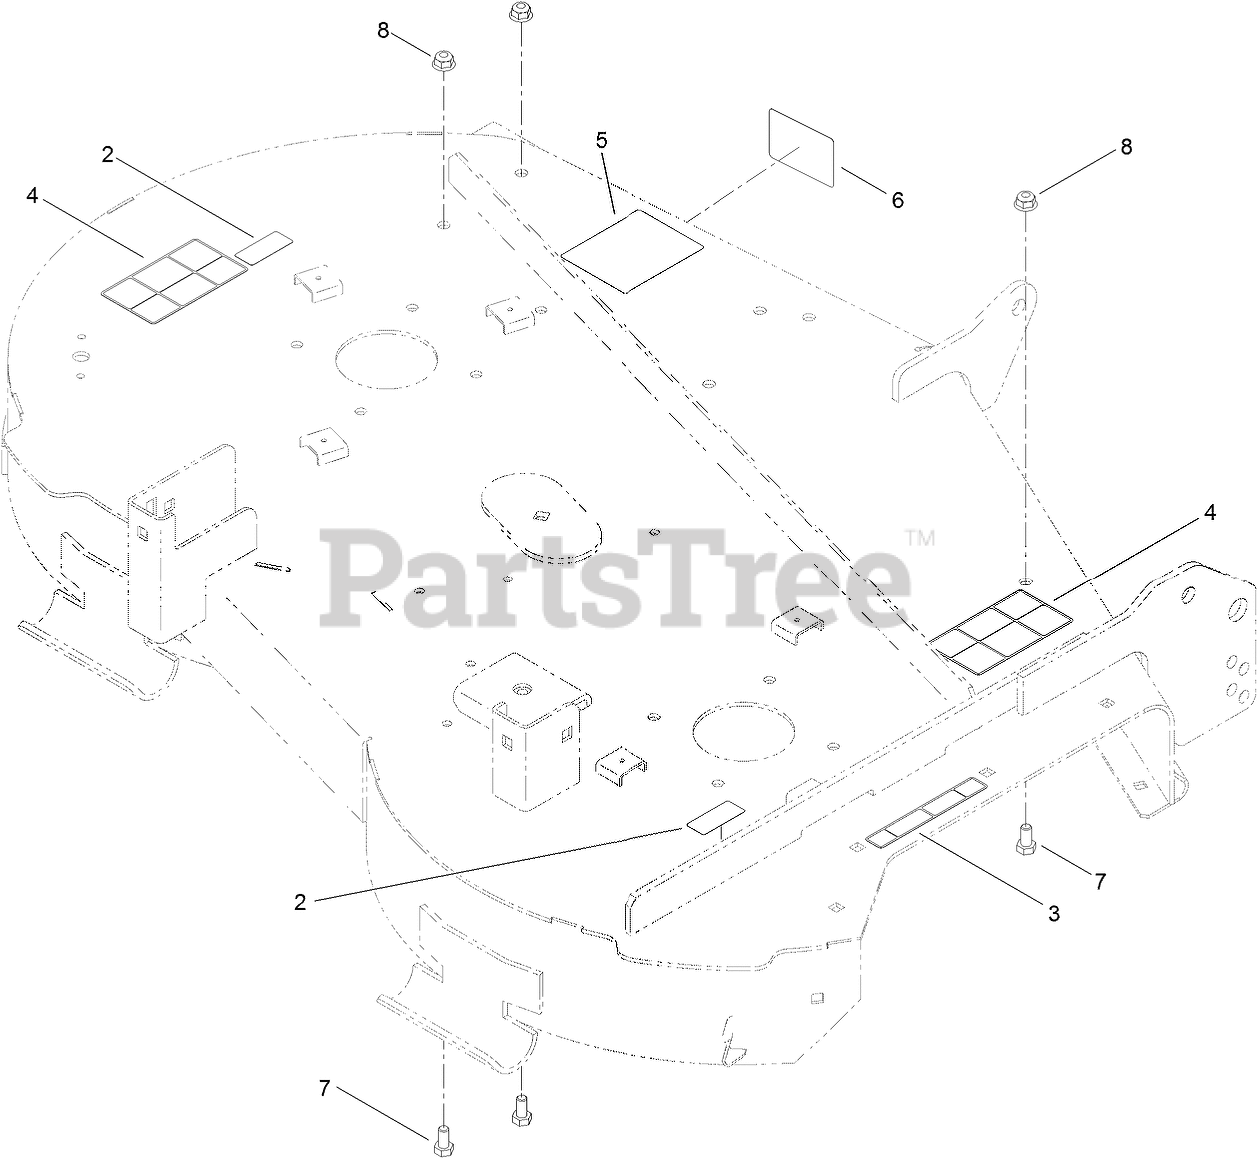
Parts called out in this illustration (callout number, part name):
2	DECAL-DANGER
3	DECAL-DANGER
4	DECAL-DANGER
5	DECAL-ROUTING, BELT
6	DECAL-SCALP, ANTI
7	SCREW-HH
8	NUT-HF, NI
